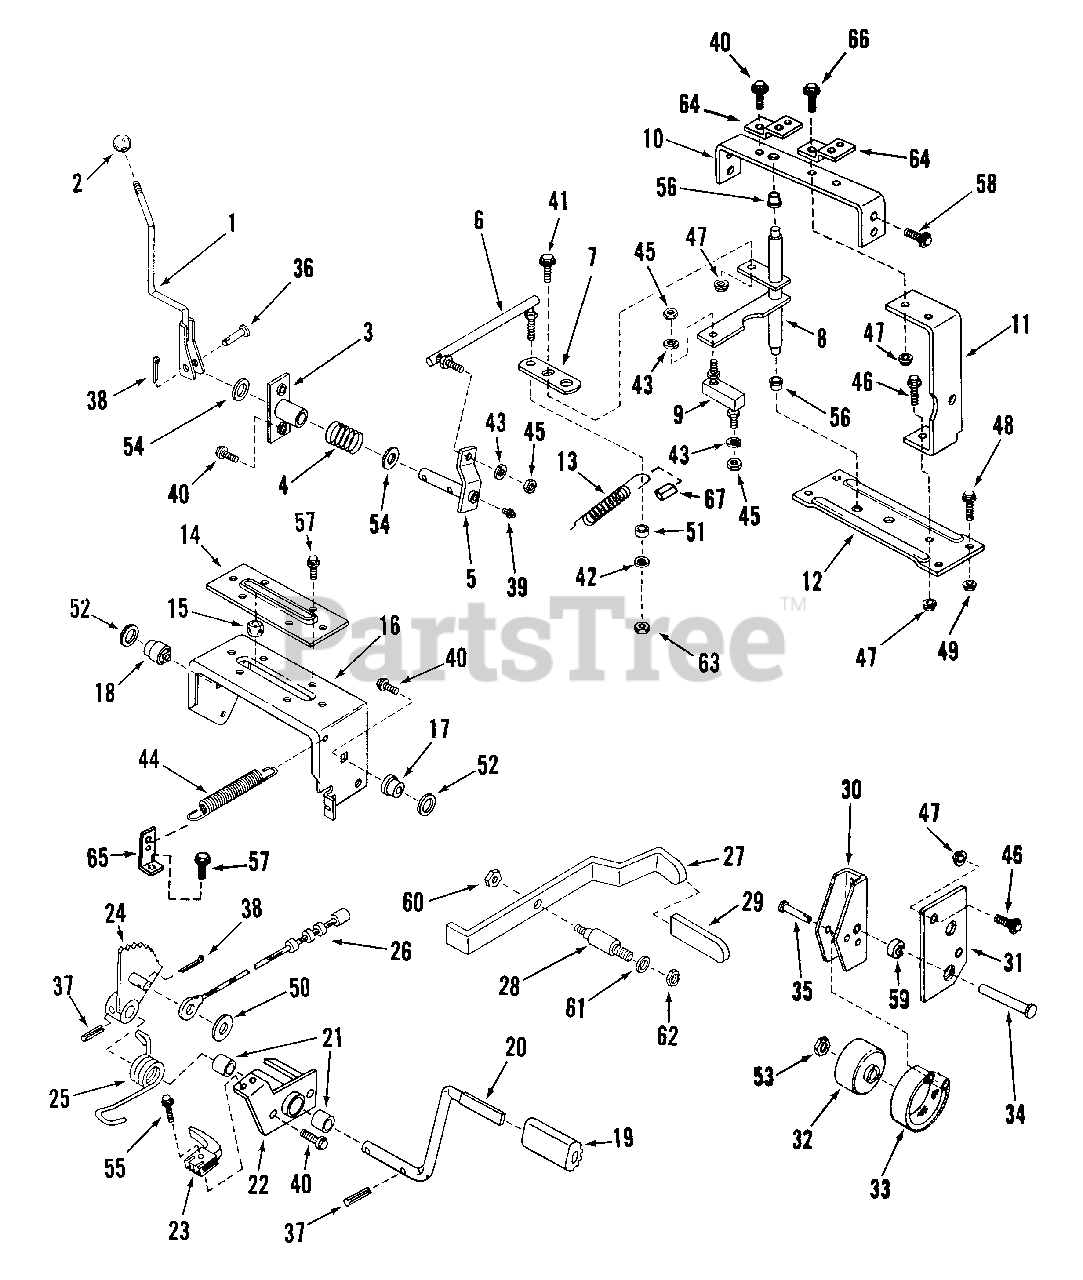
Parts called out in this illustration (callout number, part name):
1	SHIFTER, Transmission
2	KNOB, Shifter
3	PIVOT, Shift
4	SPRING, Shift Detent
5	ARM, Shifter
6	LINK, Shift-Long (8.53")(No longer available)
7	ARM, Shift Adjusting
8	ARM, Shift
9	LINK, Shift-Short
10	STRAP, Upper Cross
11	STRAP, Brake Pivot Support (No longer available)
12	STRAP, Lower Cross (No longer available)
13	SPRING, Reverse Assist (15 Coil)
14	RETAINER (PLATE), Clutch Yoke Bushing
15	BUSHING, Clutch Ball
16	YOKE, Clutch
17	BUSHING, Yoke Pivot-Short
18	BUSHING, Yoke Pivot-Long
19	PAD, Pedal
20	PEDAL, Clutch Brake
21	BEARING, Sleeve
22	BRACKET, Pedal Pivot
23	SWITCH, Clutch Interlock
24	ARM, Clutch/Brake
25	SPRING, Clutch/Brake
26	CABLE, Clutch/Brake (36.0")
27	LEVER, Parking Brake
28	STUD, Parking Brake
29	SLEEVE, Parking Brake
30	LEVER, Brake Pivot
31	SUPPORT, Brake Pivot
32	DRUM, Brake
33	BAND, Brake
34	PIN, 3/8 x 2-9/16" Clevis
35	PIN, 1/4 x 1-13/16" Clevis
36	PIN, 3/8 x 1-1/4" Clevis
37	PIN, 3/16" x 1-1/4" Roll
38	PIN, 3/32 x 3/4" Cotter
39	FITTING, Lube
40	SCREW, 5/16-18 x 5/8" Hex Flange Self-Tap
41	BOLT, 5/16-18 x 5/8" Hex Flange Lock
42	WASHER, 5/16 SAE
43	WASHER, 5/16 Split Lock
44	SPRING
45	NUT, 5/16-24 Hex
46	BOLT, 5/16-18 x 3/4" Hex Flange Lock.
47	NUT, 5/16-18 Hex Flange Lock, Grade 5
48	BOLT, 3/8-16 x 3/4" Hex Flange Lock
49	NUT, 3/8-16 Hex Flange Lock
50	WASHER, 3/8 SAE Flat
51	ROLLER, Shift Arm
52	WASHER, Shim
53	JAM-NUT, 5/8-18
54	WASHER, Thrust
55	SCREW, #10-24 x 1" Self-Tap
56	BEARING, Nylon
57	SCREW, 1/4-20 x 1/2" Hex Flange Self-Tap
58	SCREW, 3/8-16 Hex Flange Self-Tap
59	RING
60	NUT, 1/4-20 Small Flange Lock
61	WASHER, 3/8 Internal Tooth Lock
62	NUT, 3/8-16 Hex, Grade 5
63	NUT, 5/16-24 Hex Center Lock
64	BRACKET, Mounting- Rear Fender
65	CLIP, Spring Attach
66	BOLT, 5/16-18 x 1" Hex Flange Lock
67	CLIP, Spring Retainer
